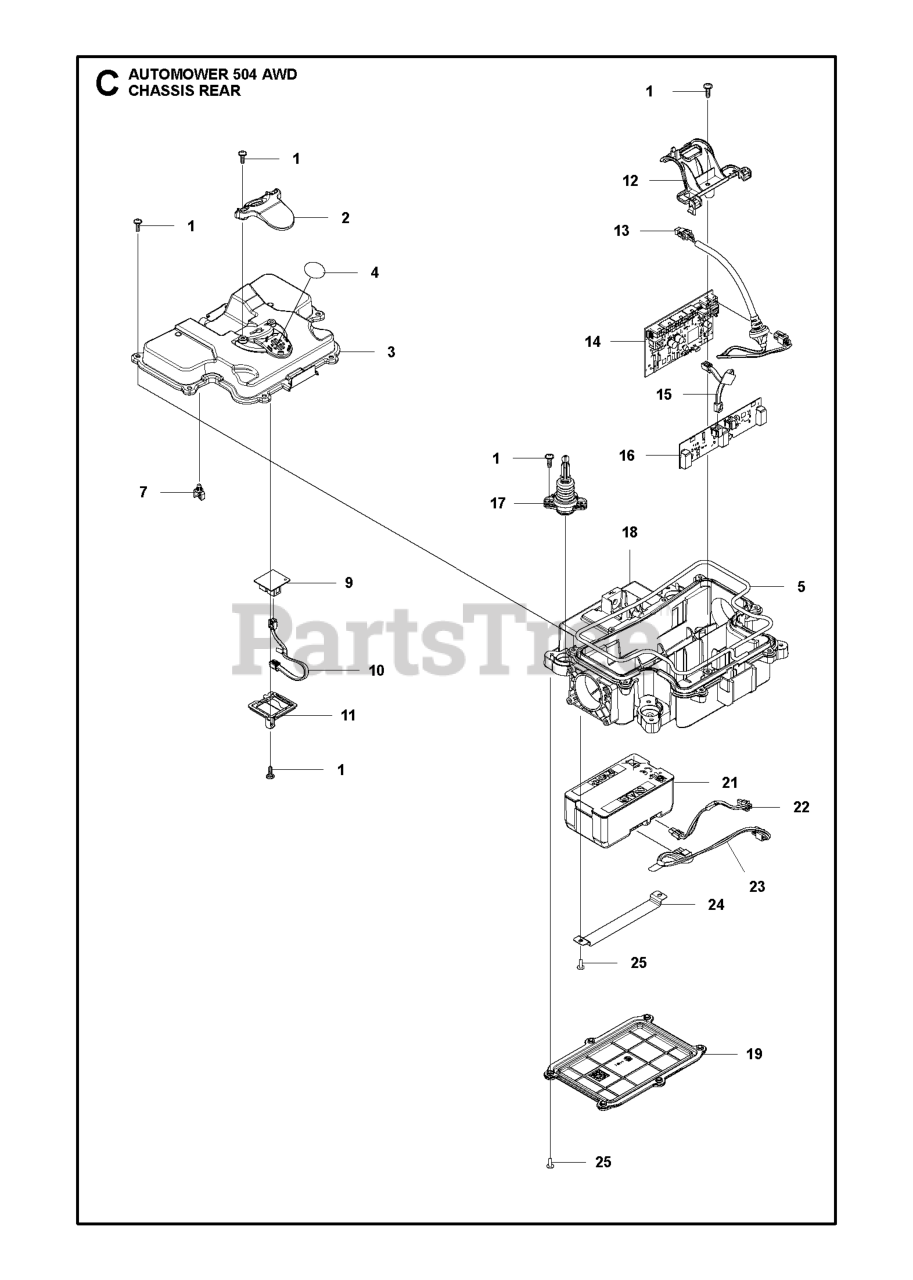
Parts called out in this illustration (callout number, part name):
1	SCREW 14MM
2	Holders
3	Chassis
4	KIT AIR FILTER KIT 305 - 10 PC
5	Seals
7	Holders
9	Circuits
10	WIRING ASSY MODULAR JACK 6/6 R
11	Holders
12	Holders
13	Wires
14	Circuits
15	WIRING ASSY MODULAR JACK 6/6 R
16	Circuits
17	JOYSTICK ASSY REAR
18	Chassis
19	Covers
22	Wires
23	Wires
24	Brackets
25	SCREW ITXPANM M4X12 A2-70 PAT
